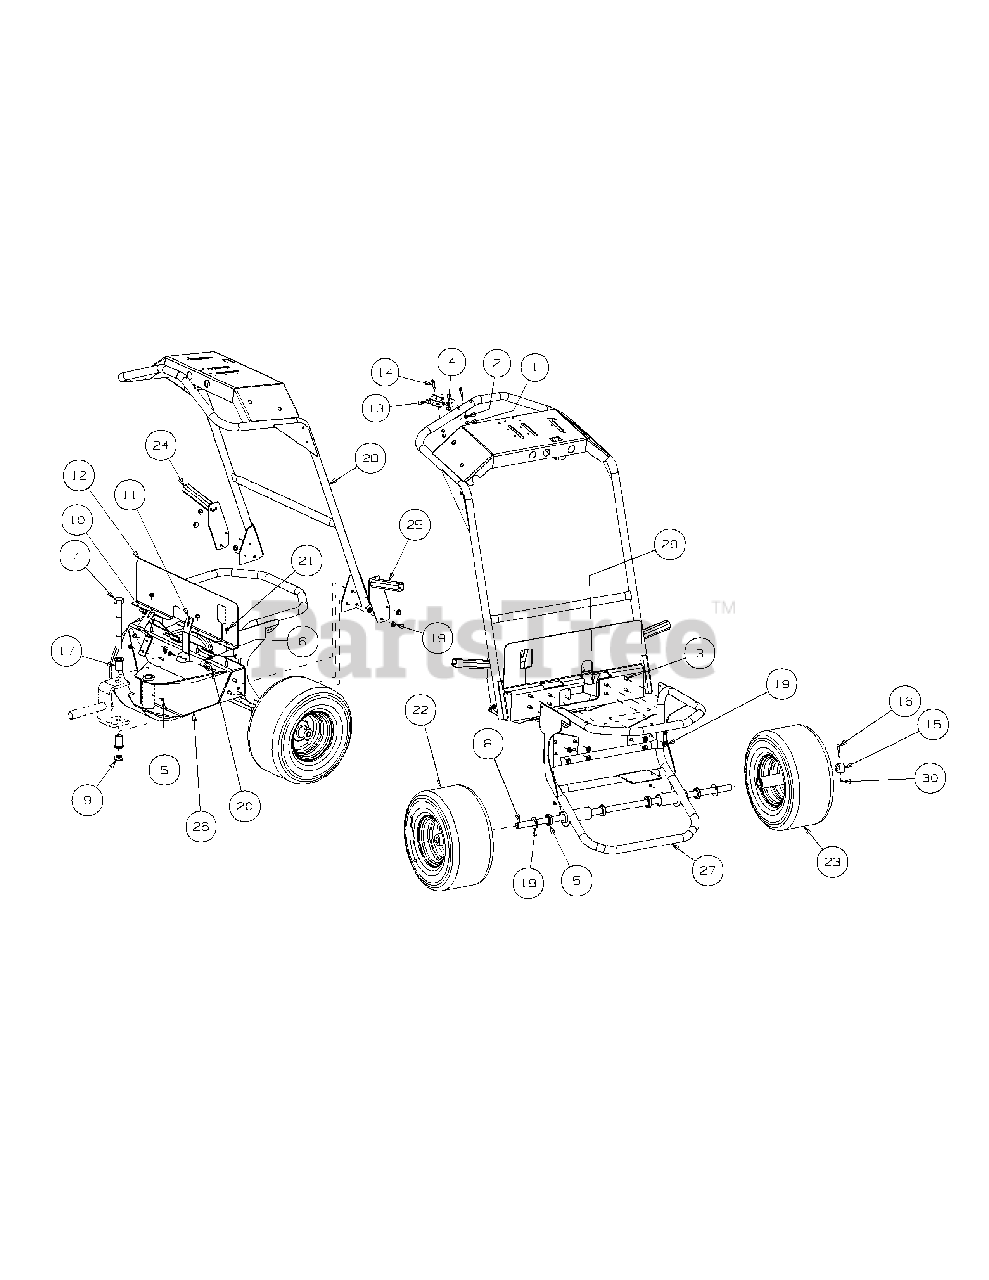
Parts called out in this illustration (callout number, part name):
1	Nut, #10-24
2	Washer, 3/16
3	Carriage Bolt, 5/16-18 x 3/4, SS
4	Washer, 1/4, SS
5	Grease Fitting, 1/4-28 x 3/16
6	Support Clamp
7	Hex Cap Screw, 3/4-16 x 6.50
8	Front Axle
9	Jam Nut, 3/4-16
10	Shut-Off Cable bracket
11	Deflector Cable bracket
12	Shield, SS
13	Speed Control Lever
14	Shoulder Bolt, 1/4 x 1.25
15	Shaft Collar
16	Screw, 10-24 x 1.25
18	Washer, .89ID x 1.5OD x .09, SS
19	Nut, 5/16-18, Flange Whiz, SS
20	Carriage Bolt, 1/4-20 x 3/4, SS
21	Nut, 1/4-20 Flange Whiz, SS
22	Drive Wheel Assmebly, 13 x 6.5-6
23	Idler Wheel Assembly, 13 x 6.5-6
24	Nozzle Bracket Assembly, LH
25	Nozzle Bracket Assembly, RH
26	Pivot Assembly
27	Front Frame bearing Assembly Includes:
27	Grease Fitting, 1/4-28 x 3/16
27	Axle Bearing
28	Handle Weldment
29	Nozzle Bracket, Center
30	Nut, #10-24, Nylon Lock
31	Axle Bearing
